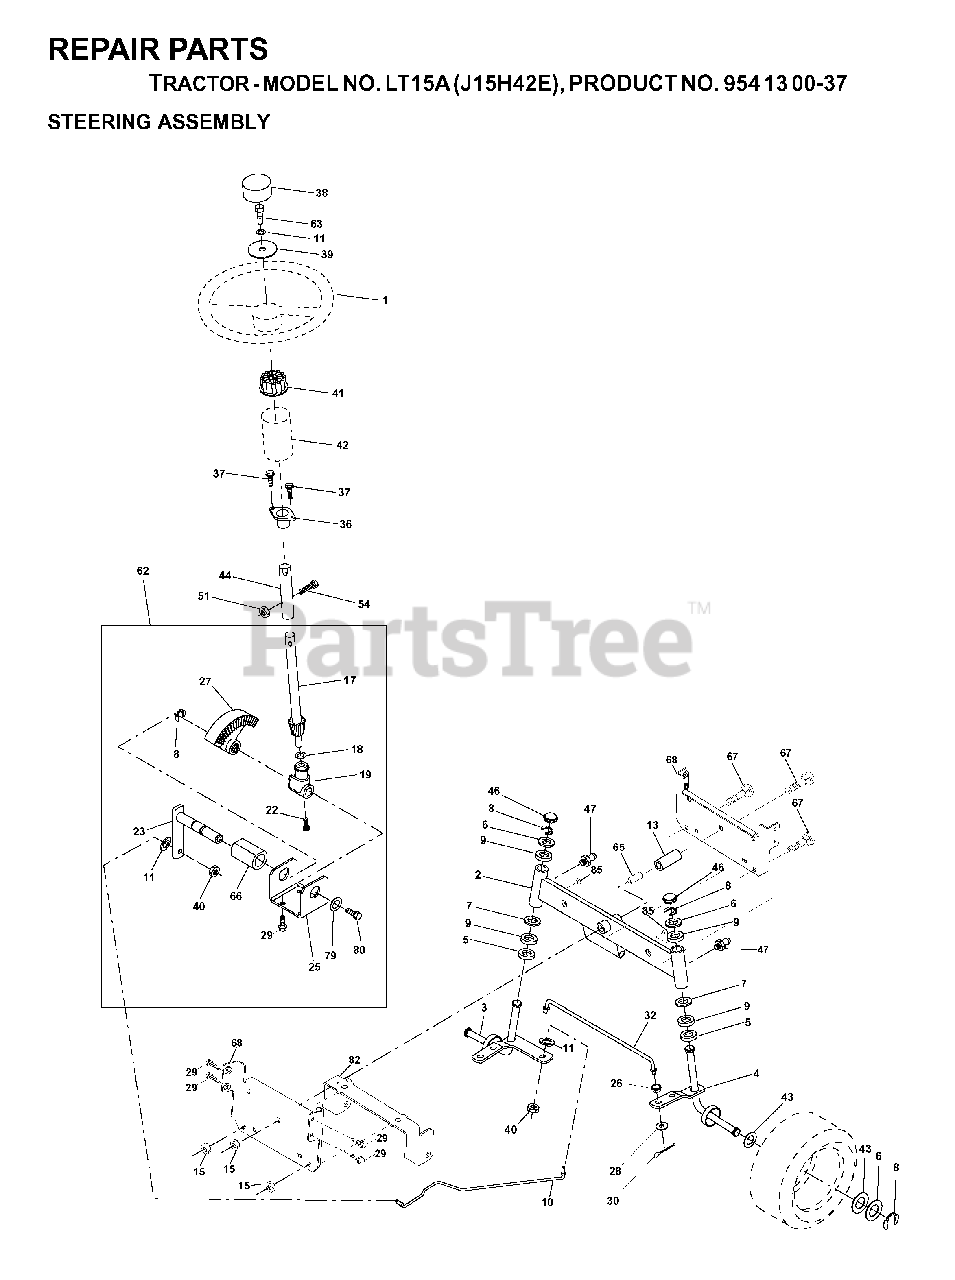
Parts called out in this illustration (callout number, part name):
2	AXLE ASSY
3	SPINDLE.ASM.LH.15"TIRES
4	SPINDLE.ASM.RH.15"TIRES
8	RING CLIP
9	BRNG T
10	DRAGLINK.15".TIRES
11	WASHER, LOCK 3/8
13	TUBE, PIVOT AXLE
15	NUT
17	SHAFT ASM STEERING
18	THRUST WASHER
19	STEERING SHAFT SUPPORT
22	SCREW.HX.WSH.HD
23	SHAFT ASSY PITTMAN
25	BRACKET STEERING
26	BUSHING.DRAGLINK
27	GEAR.SECTOR
28	WASHER
29	SCREW 3/8-16X3/4
30	COTTER PIN
32	TIE ROD
36	BUSHING, STEERING
39	WASHER 13/32 X 2-3/8 X 12 GA
40	GRIPCO NUT
41	STEERING WHEEL ADAPTOR
42	BOOT.STEERING.SHAFT.BLACK
44	EXT SHAFT STEERING
46	CAP.SPINDLE
47	ZERK M
51	NUT.71038.31-18.HEX.NYLOCK
54	BOLT.5/16-18X1-1/4 FULL.THREAD
62	STEERING KIT
63	BOLT
65	SPACER BRACE AXLE
66	BEARING ARM
67	BOLT CARRIAGE
68	BRACE.AXLE.15"TIRES
80	BOLT.HX.NYLON3/8-16X
82	BRACKET
85	FASTENER.XMAS.TREE
